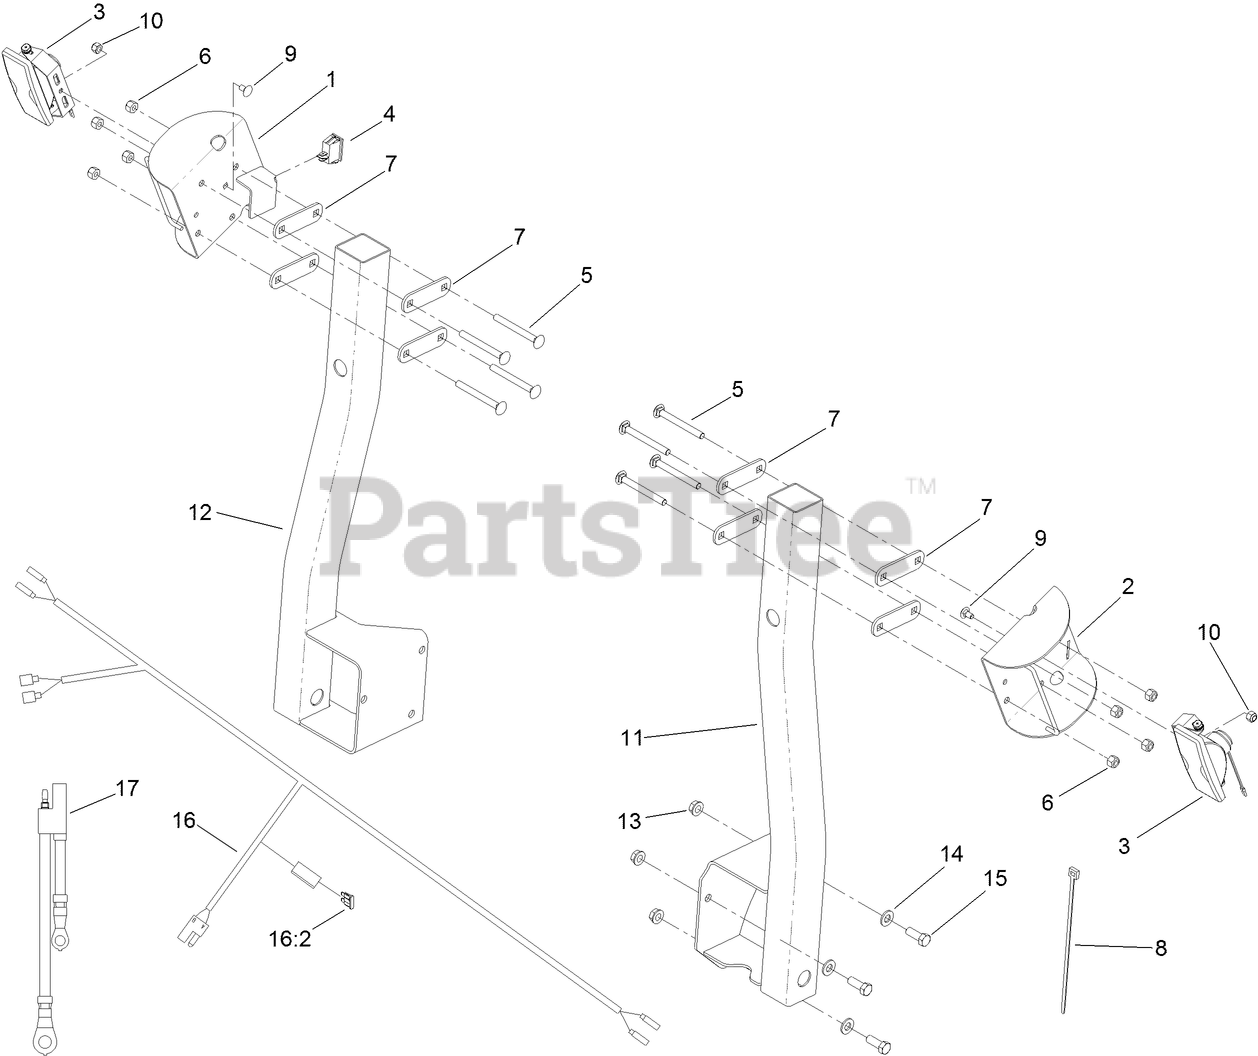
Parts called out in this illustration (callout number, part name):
1	BRACKET-RH, SWITCH and LIGHT
2	BRACKET-LIGHT, LH
3	LIGHT-HALOGEN, 35 WATT
4	SWITCH-ROCKER
5	SCREW-CARR
6	NUT-LOCK, NI
7	LIGHT PLATE KIT
8	TIE-PLASTIC
9	SCREW-CARR
10	NUT-LOCK, NI
11	POST-LIGHT, LH
12	POST-LIGHT, RH
13	NUT-HHF, WHIZ
14	WASHER-FLAT
15	SCREW-HH
16	LIGHT HARNESS KIT
16:2	FUSE-BLADE, 10 AMP
17	PIGTAIL CONNECTOR ASM
